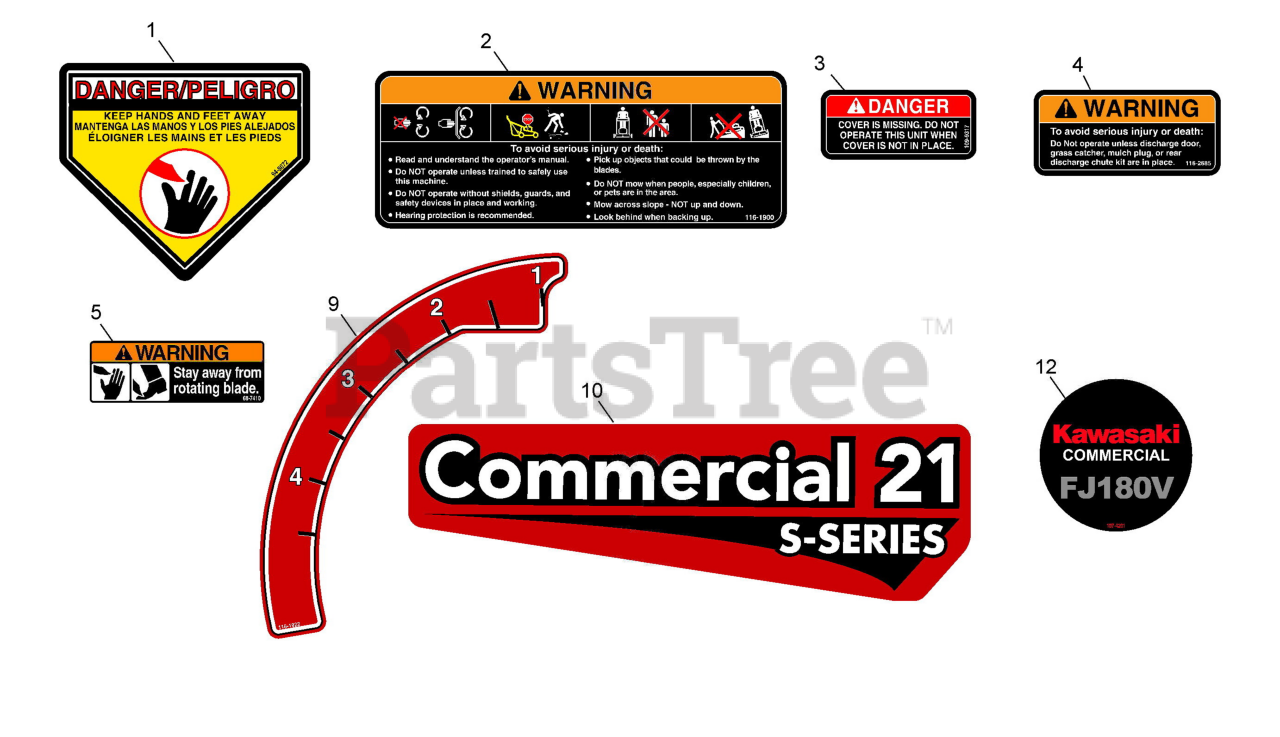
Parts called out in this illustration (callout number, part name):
1	DECAL-DANGER
2	DECAL-WARNING
3	DECAL-COVER MISSING
4	DECAL-WARNING DOOR SM
5	DECAL-BLADE
9	DECAL-HEIGHT OF CUT
10	DECAL-COMM 21 S-SERIES
12	DECAL-RECOIL
